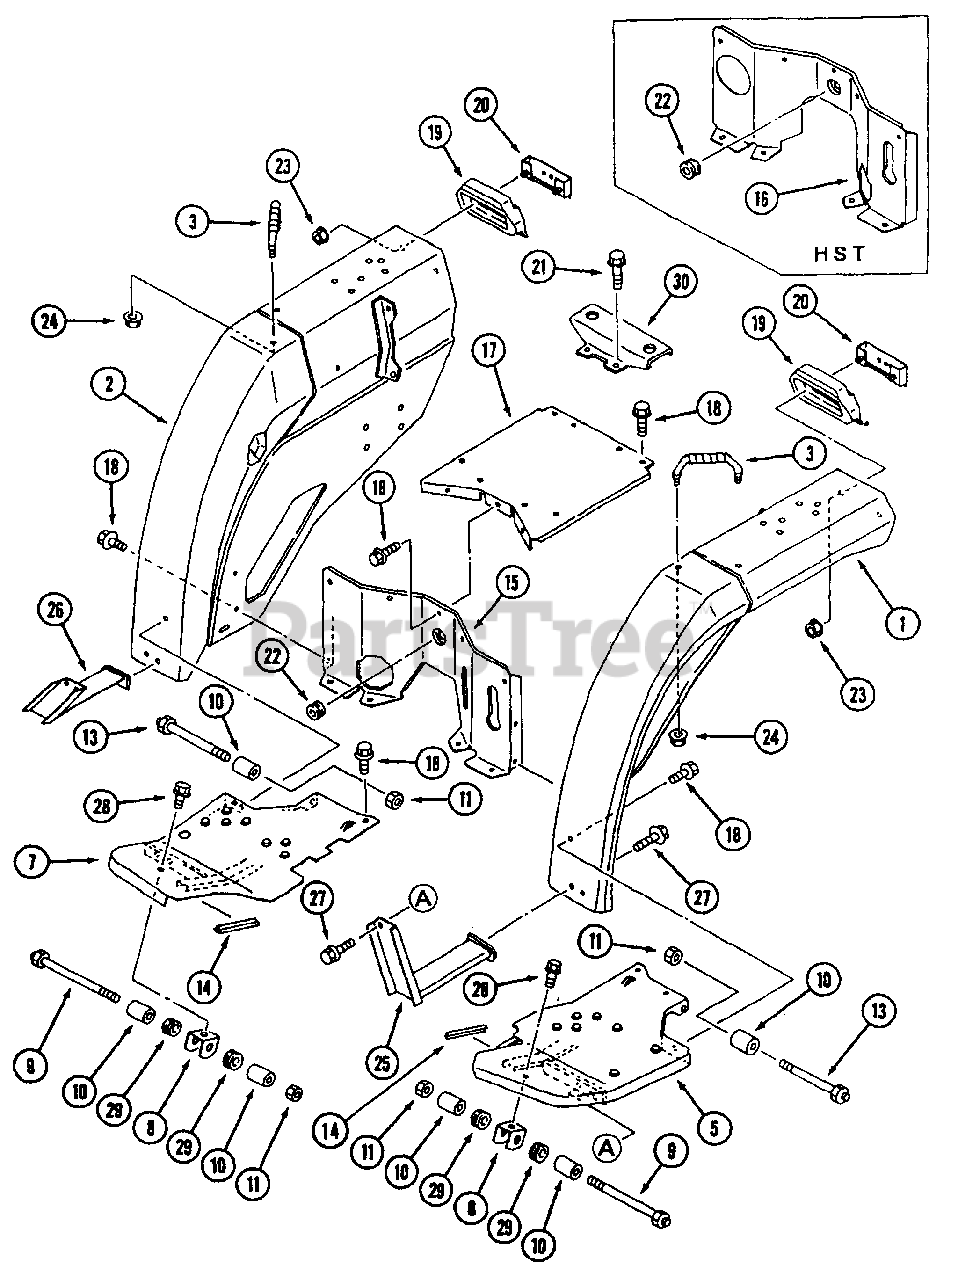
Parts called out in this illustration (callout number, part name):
16	Cover, Front
20	Bracket
25	Step, Sub L.H.
26	Step, Sub R.H.
